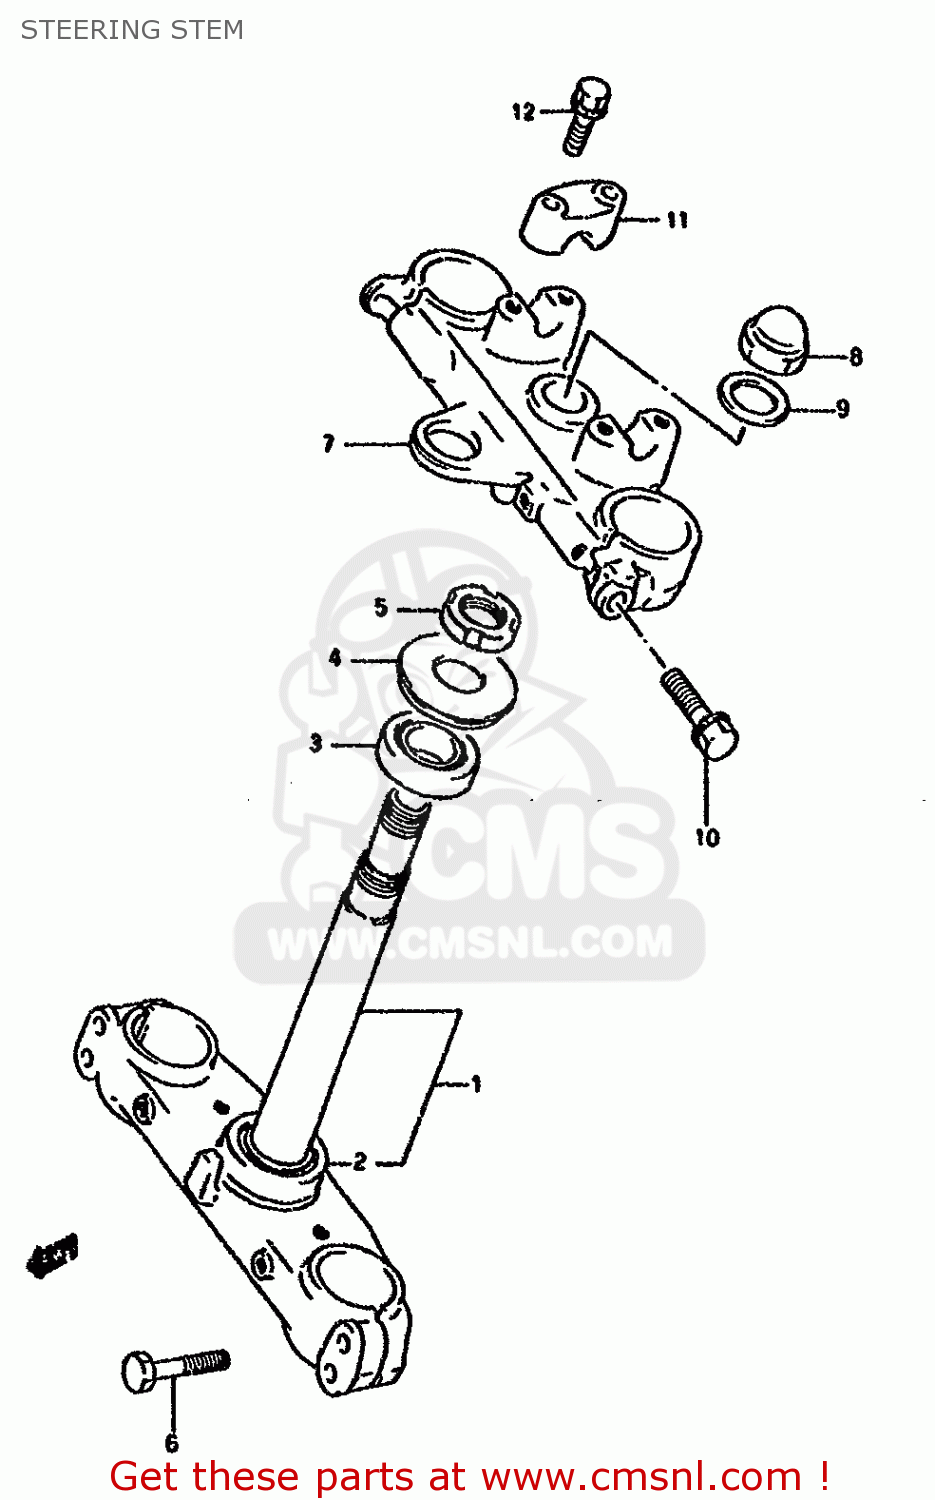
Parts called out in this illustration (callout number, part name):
1	STEM,STEERING
2	BEARING(30X55X17)
3	TAPER,ROLLER BEARING
4	SEAL,STEERING UPR DUST
5	NUT,STEERING STEM
6	BOLT,STEM(8X50)
7	HEAD,STEERING STEM
8	NUT
9	WASHER(22.5X32X1.6)
10	BOLT,UPPER BRACKET
11	HOLDER,HANDLE UPR
12	BOLT
